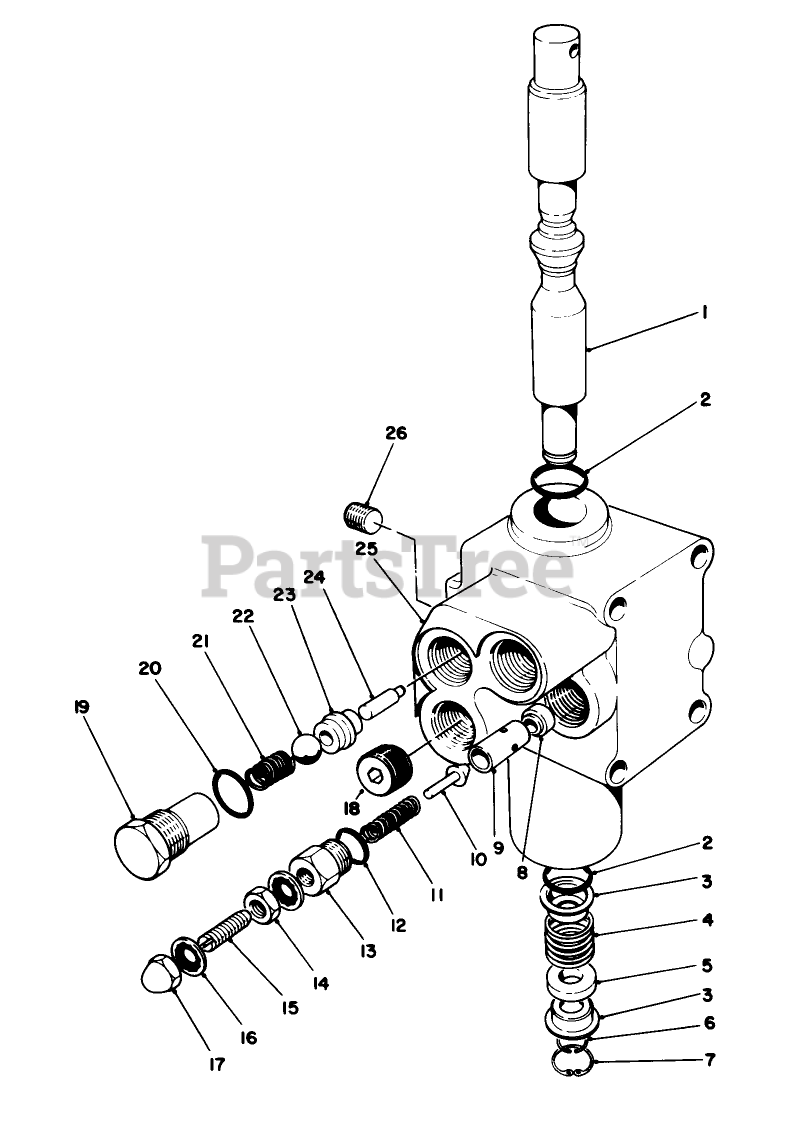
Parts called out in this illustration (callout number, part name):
1	SPOOL
2	O-RING
3	RETAINER
4	SPRING
5	FLOAT SPACER
6	RING-SNAP
7	RING-SNAP
8	SEAT-RELIEF
9	Guide
10	Plunger
12	"O" Ring
13	Cap-PV Adjustment
14	Jam Nut
15	Set Screw
16	Stat O-Seal
17	Nut-Acorn
20	O-RING
21	SPRING
23	SEAT-VALVE
